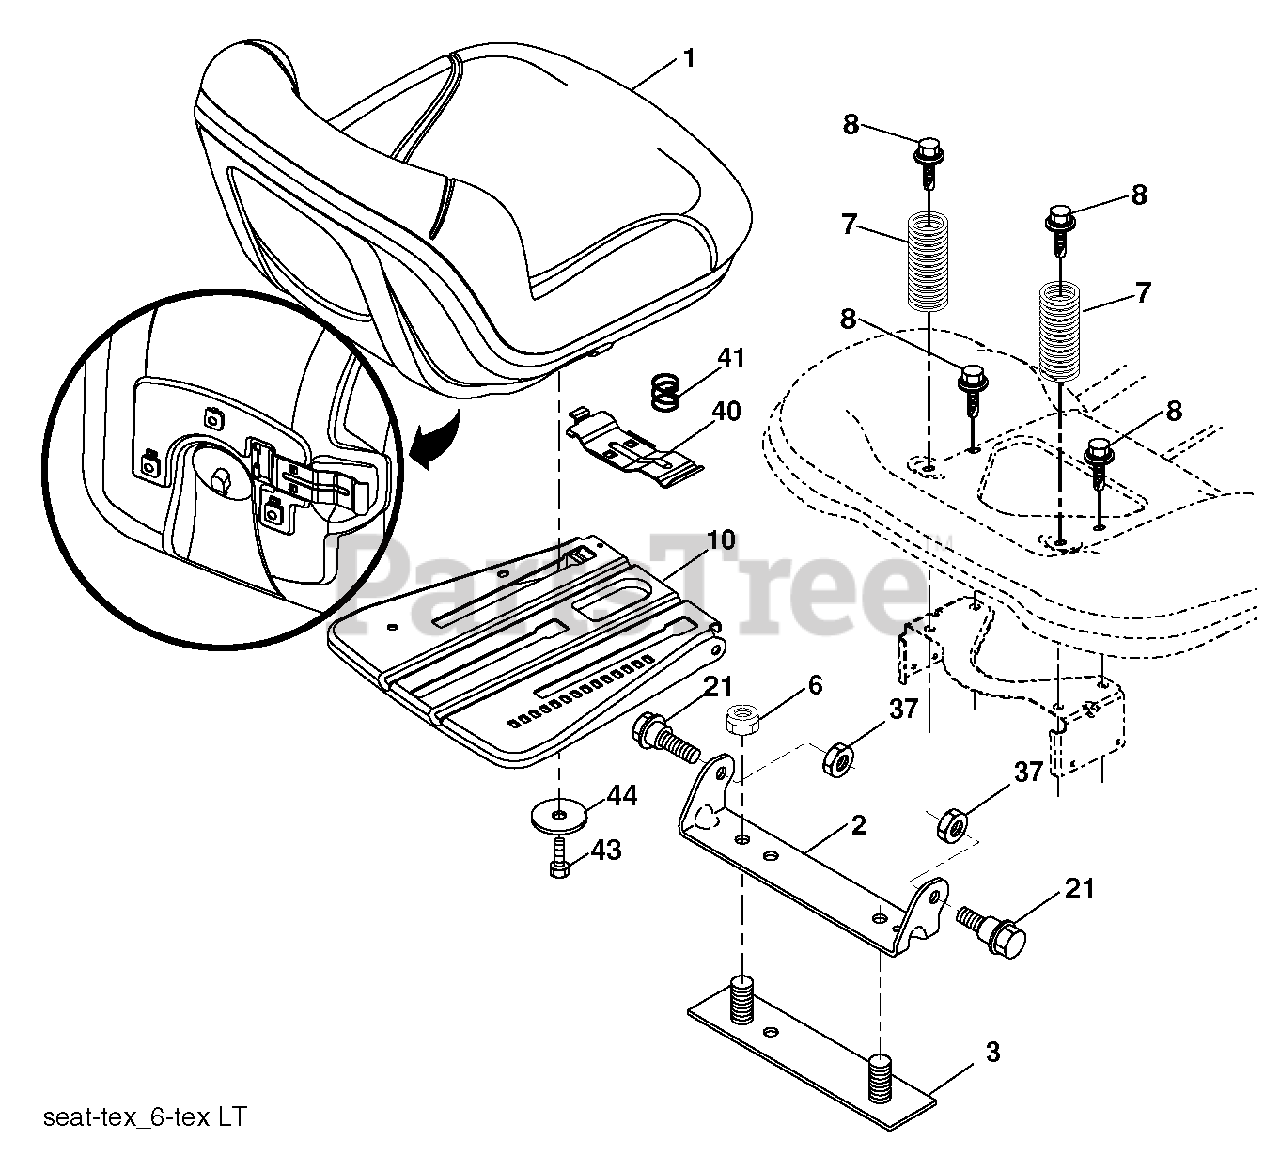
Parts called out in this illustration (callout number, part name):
1	SEAT.TH130.GREY.HUSQ.TEX
2	BRKT.PIVOT.FENDER
3	STRAP
6	NUT
7	SPRING COMPRESSION
8	BOLT, 5/16-18 X 1 3/4
10	PAN.ASM.SEAT.3PT
21	BOLT.SHOULDER.5/16-18
37	NUT.71038.31-18.HEX.NYLOCK
40	HANDLE.SLIDE.SEAT.TEX.BLACK
41	SPRING.LATCH.SEAT.TEX
44	WASHER 13/32 X 2-3/8 X 12GA
